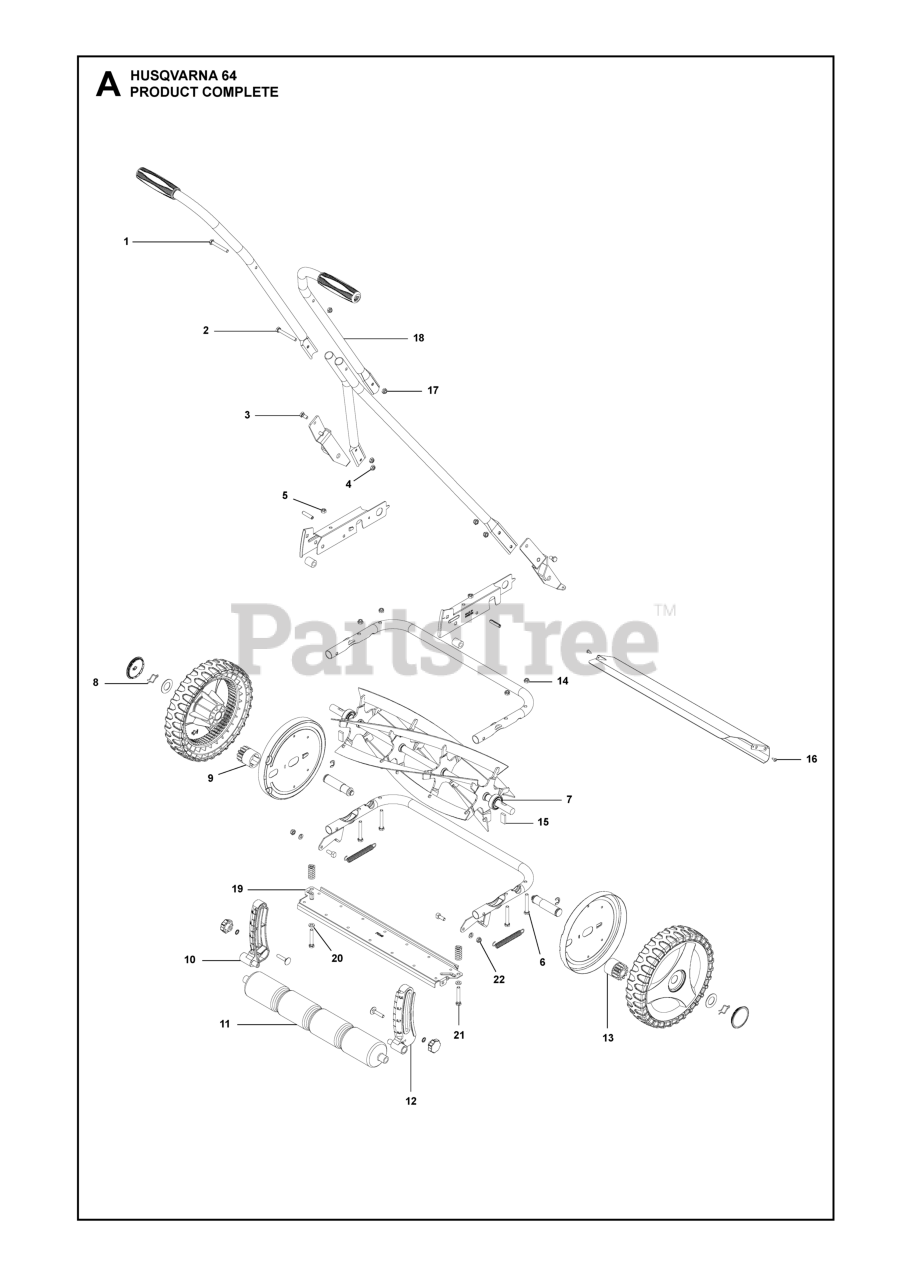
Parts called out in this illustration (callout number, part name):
2	SCREW M6X50
4	LOCKNUT M6
9	GEAR **
10	HEIGHT GAUGE
12	HEIGHT GAUGE
13	GEAR **
14	LOCKNUT M6
17	LOCKNUT M6
22	LOCKNUT M6
